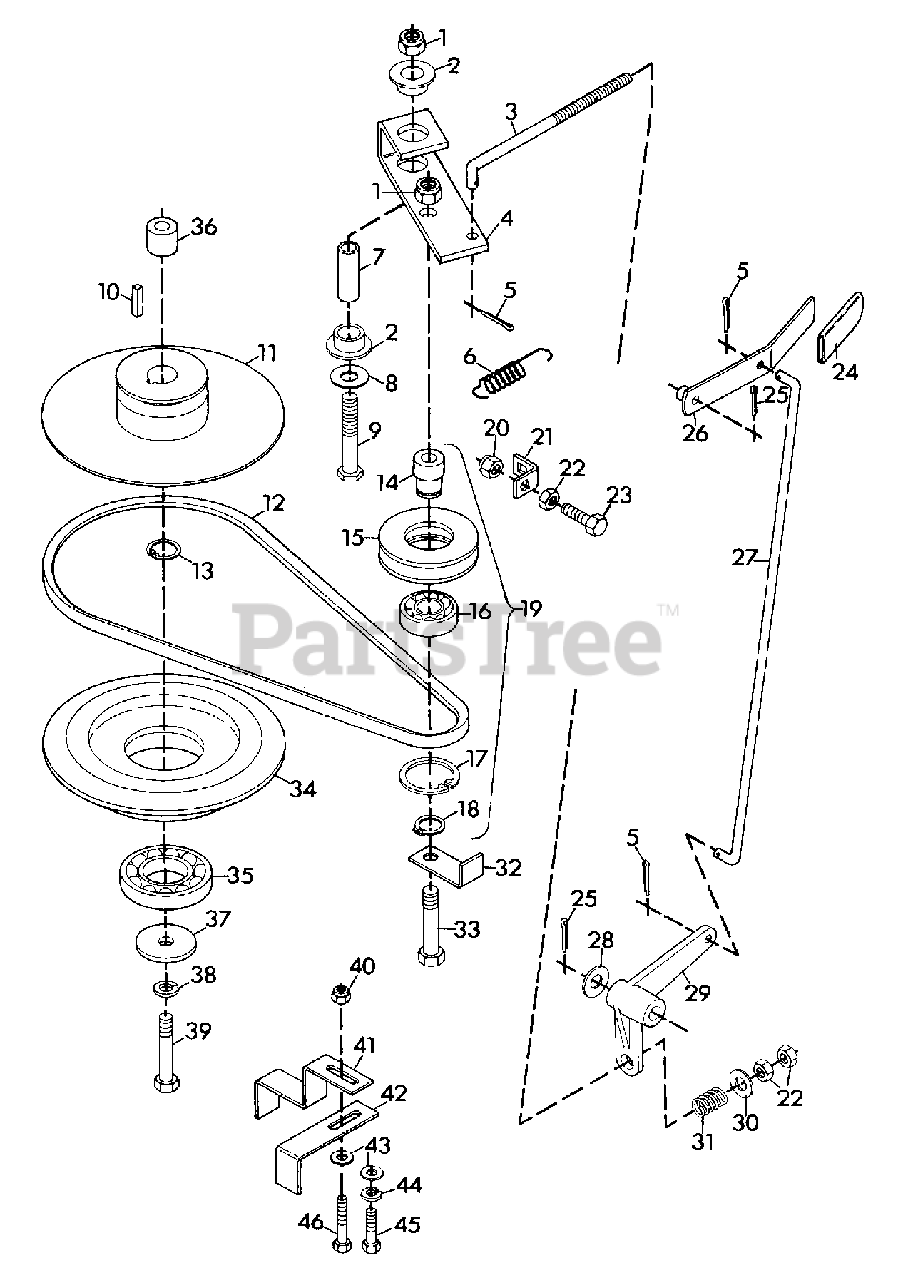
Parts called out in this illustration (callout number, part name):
1	NUT, LOCK 1/2-13
2	BUSHING, NYLON .76X1X.6 FLANGE
3	ROD, PTO CLUTCH ACTUATING
4	ARM, IDLER PIVOT
5	PIN, COTTER .09X.75
6	SPRING, PTO RETURN
7	SPACER
8	WASHER, FLAT .531X1.250X.100
9	BOLT, HEX 1/2-13X2.75 SPECIAL
10	KEY, SQUARE .250X1.250
11	HUB, PTO AND DRIVE CLUTCH
12	BELT, ENGINE-TRANSMISSION DRIVE
13	RING, RETAINING
14	BUSHING
15	SHEAVE, IDLER
16	BEARING, BALL
17	RING, RETAINING
18	RING, RETAINING
19	ASSEMBLY, IDLER SHEAVE
20	NUT, LOCK 3/8-16
21	TAB, SPRING
22	NUT, HEX 3/8-16
23	BOLT, HEX 3/8-16X1.50
24	GRIP, PTO LEVER
25	PIN, COTTER .125X1.00
26	WELDMENT, PTO CONTROL
27	ROD, PTO CONTROL
28	WASHER, FLAT .531X1.062X.095
29	LEVER, PTO CLUTCH
30	WASHER, FLAT .406X.812X.065
31	SPRING, COMPRESSION 1.0X.78
32	GUIDE, BELT
33	BOLT, HEX 1/2-13X2.50
34	SHEAVE, MOWER CLUTCH
35	BEARING, BALL 1.574X3.149X.708
36	SPACER, ELECTRIC CLUTCH
37	WASHER, SPECIAL FLAT
38	WASHER, LOCK 7/16 REG.
39	BOLT, HEX 7/16-20X2.50
40	NUT, LOCK 5/16-18
41	GUIDE, PTO V-BELT
42	GUIDE, V-BELT
43	WASHER, FLAT .344X.688X.065
46	BOLT, HEX 5/16-18X1.75
